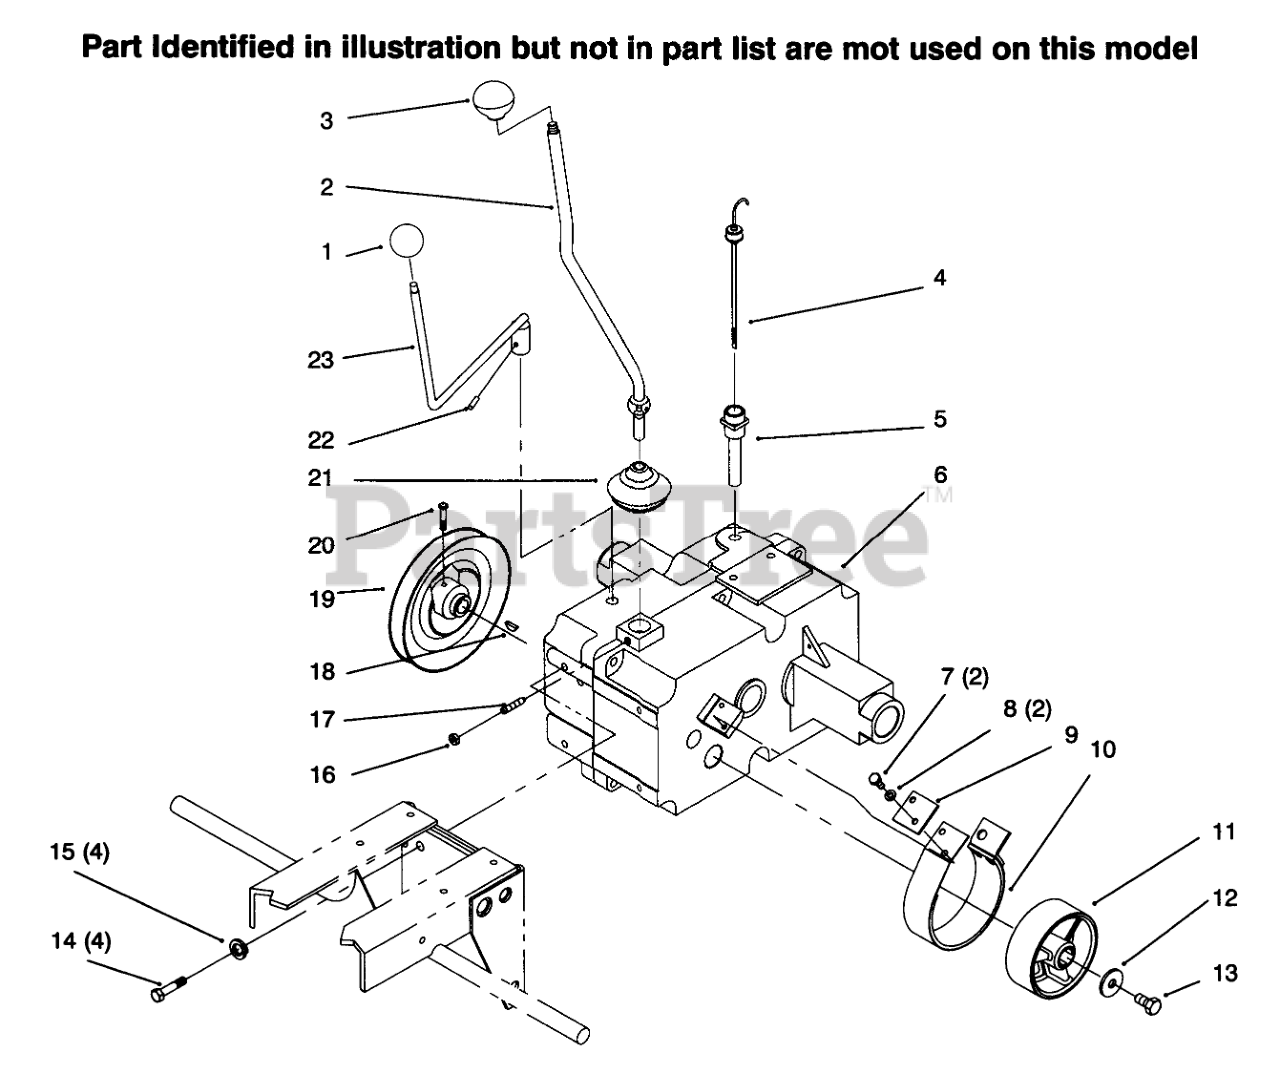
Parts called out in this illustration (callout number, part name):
2	ASM-Rod
4	Dipstick
5	NIPPLE-FILL, TRANSMISSION
6	Trans ASM
7	SCREW-HH
8	WASHER-LOCK
9	Plate-Stop
10	BRAKE BAND ASM
11	DRUM-BRAKE
12	WASHER
13	SCREW-HEX HD CAP
14	SCREW-HH
15	WASHER-LOCK
16	NUT-HEX
17	SETSCREW
18	KEY-HI PRO
19	PULLEY-TRANSMISSION
20	SCREW-SQH
21	COVER-DUST
22	PIN-SPIROL
23	SHIFT ROD ASM
24	DECAL-UNIDRIVE
